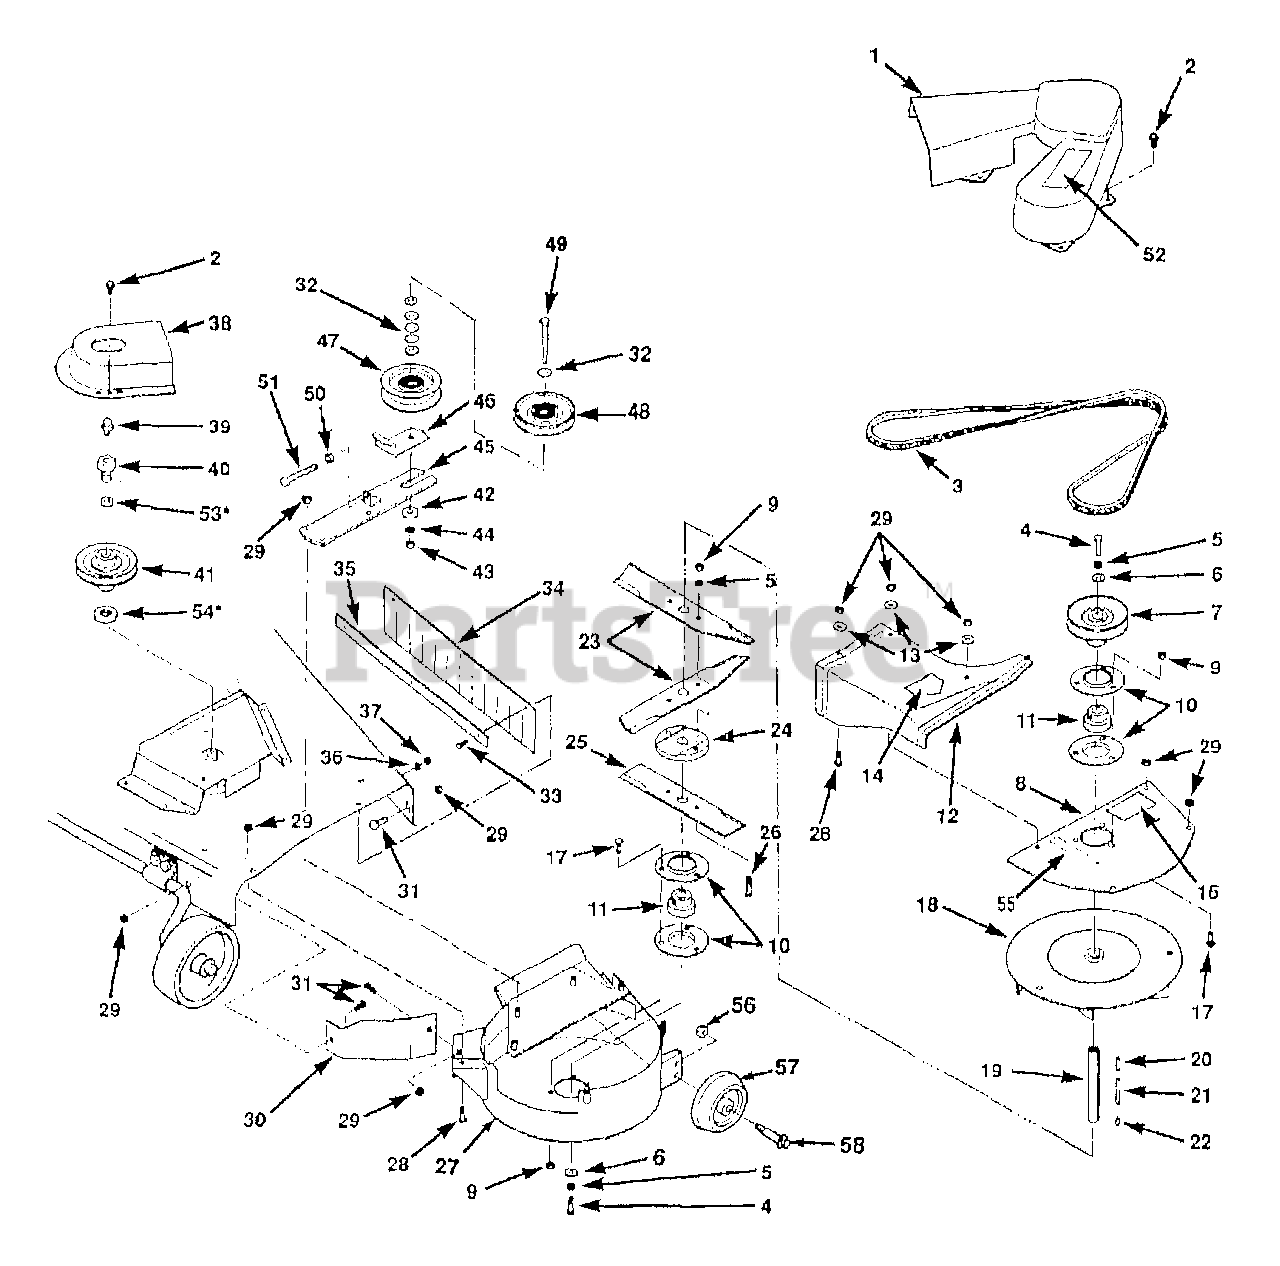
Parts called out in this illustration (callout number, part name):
1	COVER-BELT
2	SCR-THRD FRM 1/4-14X.50
3	BELT-DRIVE
4	SCR-HH 5/16-18X1.0 G5 ZP
5	WASHER-LK .312 ZP
6	WASHER-.312 X 1.378
7	SHEAVE-DRIVEN
8	HOUSING-COVER
9	NUT-TOP/LK 5/16-18 ZP
11	BEARING-BALL
12	DEFLECTR-DISCH W/DECAL
13	WASHER-FLAT 5/16 SAE
14	DECAL-OPEI CAUTION
16	DECAL-BELT INSTALLATION
17	SCR-CARR 5/16-18X.62 G2 ZP
20	KEY-.188 SQ X 1.0
21	KEY-.188 SQ X 2.0
22	KEY .188 SQ X.343
23	BLADE-11.375"
24	HUB-BLADE
25	BLADE-10"
26	SCR-HH 5/16-18X1.25 G5ZP
27	HOUSING-FAN
28	SCR-HFLK 5/16-18X.75 ZP
29	NUT-HFLK 5/16-18 ZP
30	BAFFLE-REAR
30	ASSM-REAR BAFFLE
31	SCR-CARR 5/16-18X1.0 G2 ZP
32	WASHER-FLAT 3/8 SAE
33	SCR-HH 10-24X.50
34	SHIELD-DEFLECTOR
35	STRIP-RETAINER
36	WASHER-LK M10
37	NUT-HEX M10-24
38	GUARD-BELT
39	FITTING-GREASE 1/4-28X2.00
40	LOCK-SHEAVE
41	PULLEY-DRIVE
42	WASHER-FLAT 1.25X.406X.179
43	NUT-HEX 3/8-16 ZP
44	WASHER-LK .375 @ DEPL
45	ASSM-IDLER BRACKET
46	BRKT-ADJUSTMENT
48	PULLEY-IDLER
49	SCR-HHC 3/8-16X3.25
50	NUT-HEX 5/16-18 ZP
51	SCR-HHM 5/16-18X2.75
52	DECAL-IDENTIFICATION
53	SPACER-.625X.406X.179
54	SPACER-1.25X.781X.179
55	DECAL-DANGER
56	DECAL-CUTTING LINE
57	WHEEL-GAGE
58	COVER-TOP
